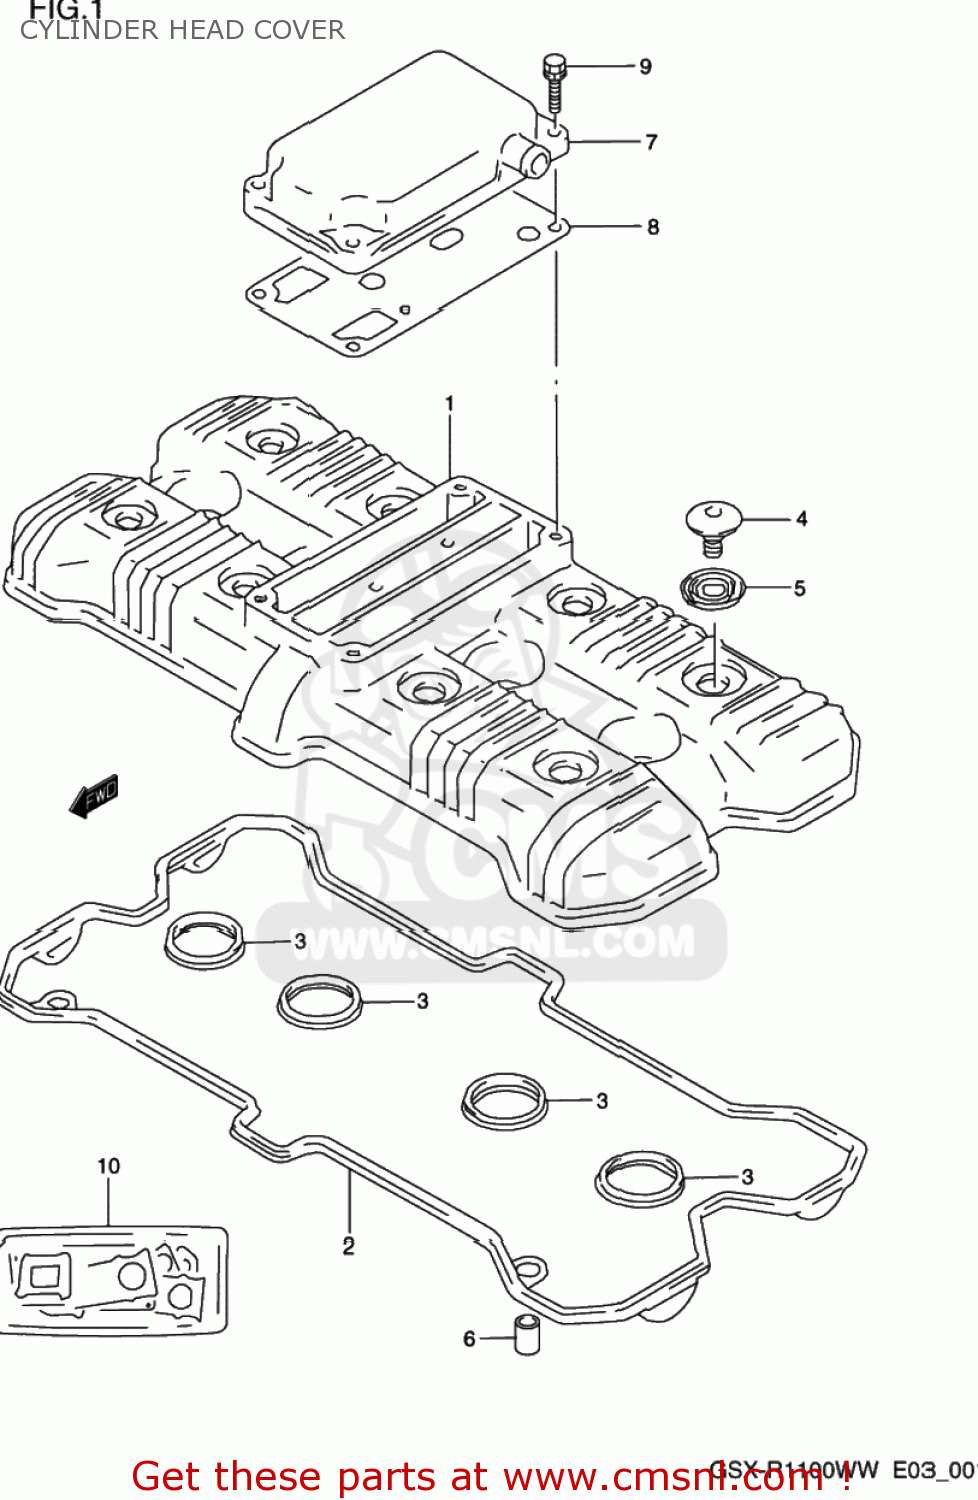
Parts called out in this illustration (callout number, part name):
1	COVER,CYLINDER HEAD
2	GASKET,CYL HEAD COVER NO.1
3	GASKET,CYL HEAD COVER NO.2
4	BOLT(7X17.5)
5	WASHER(10.6X25.5X2.3)
6	PIN(6.2X8X11)
7	COVER,BREATHER
8	GASKET,BREATHER COVER
9	BOLT
10	GASKET SET (NAS)
